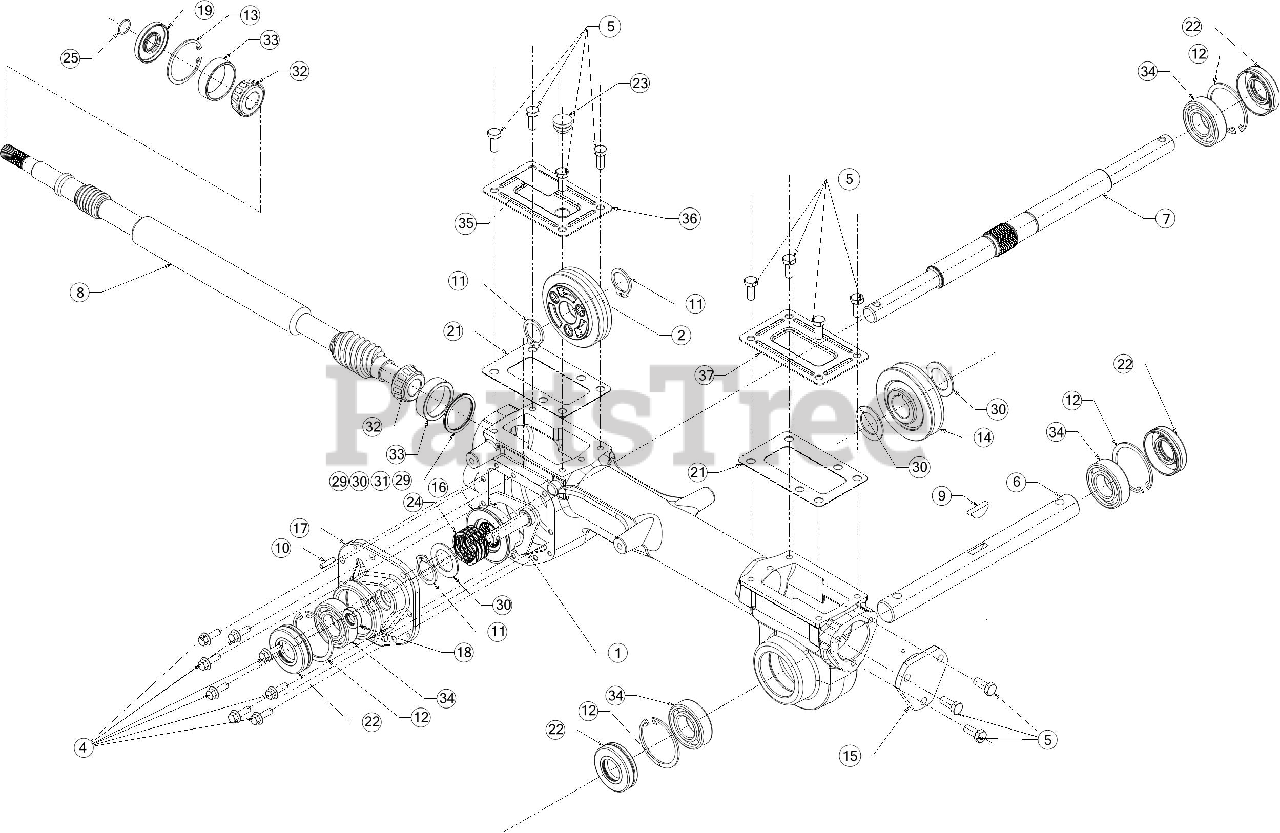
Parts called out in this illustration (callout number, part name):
1	WHEEL DRIVE SHAFT YOKE ASSEMBLY
2	WORM GEAR ASSEMBLY
2	SCREW 5/16-18X.625
3	TILLER TRANSMISSION HOUSING
4	SCREW 1/4-20 X .75 GR5
5	SCREW 5/16-18 X .75 GR5
6	TILLER SHAFT
7	WHEEL AXLE SHAFT
8	WORM DRIVE SHAFT
9	KEY-HI PRO .25 X 1
10	DOWEL PIN
11	RETAINING RING
12	RETAINING RING
13	RETAINING RING
14	WORM GEAR 30 T
15	BEARING COVER
16	DISCONNECT COLLAR
17	TILLER HOUSING COVER
18	OIL SEAL .5000 X .8750 X .2500
19	OIL SEAL .750 SHF X 1.783
21	GEAR HOUSING GASKET
22	OIL SEAL 1.00 SHF X 2.00 BORE
23	RUBBER OIL PLUG
24	WHEEL DRIVE SPRING
25	WIRE RING
29	FLAT WASHER 1.500X1.750X0.010
30	WASHER 1.010X1.560X.060
32	BEARING CONE
33	BEARING CUP
34	BALL BEARING
35	LABEL
36	TRANSMISSION COVER
37	TRANSMISSION COVER
